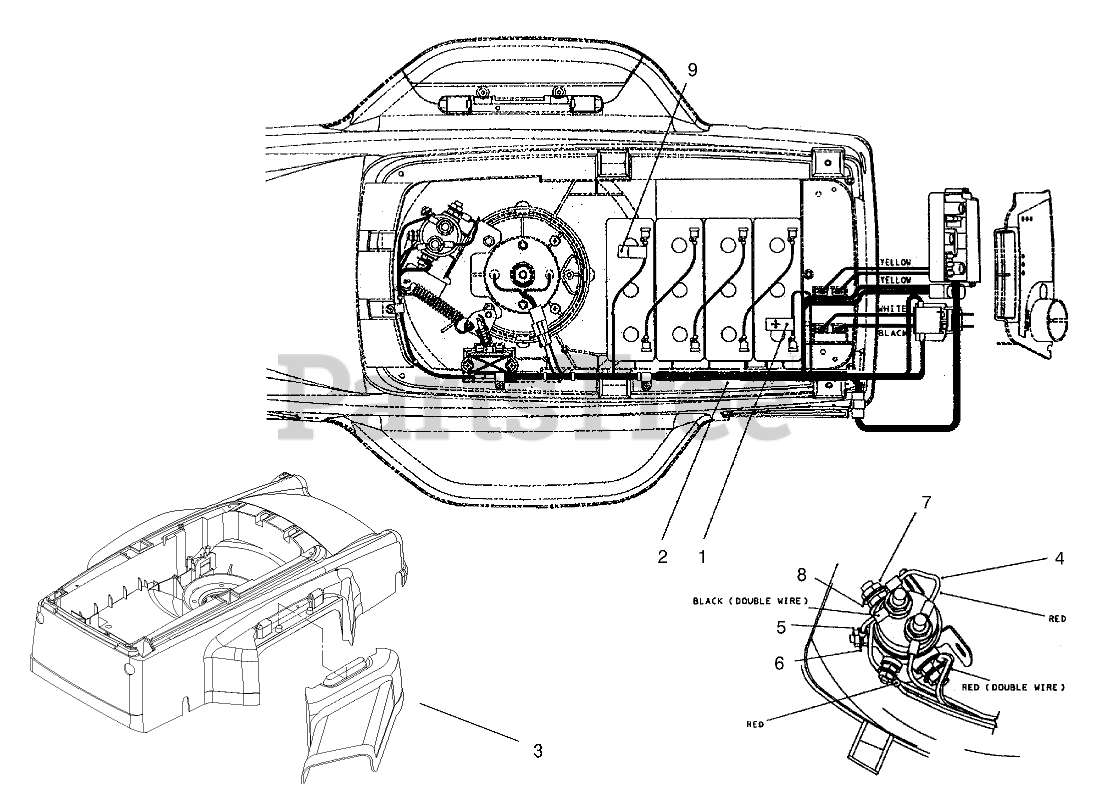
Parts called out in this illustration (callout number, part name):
1	DECAL - POSITIVE
2	HARNESS - WIRE
3	CHUTE - SIDE
4	HARNESS-WIRE JUMPER
5	NUT-HJ
6	WASHER-LOCK
7	NUT-JAM
8	WASHER-LOCK
9	DECAL - NEGATIVE
